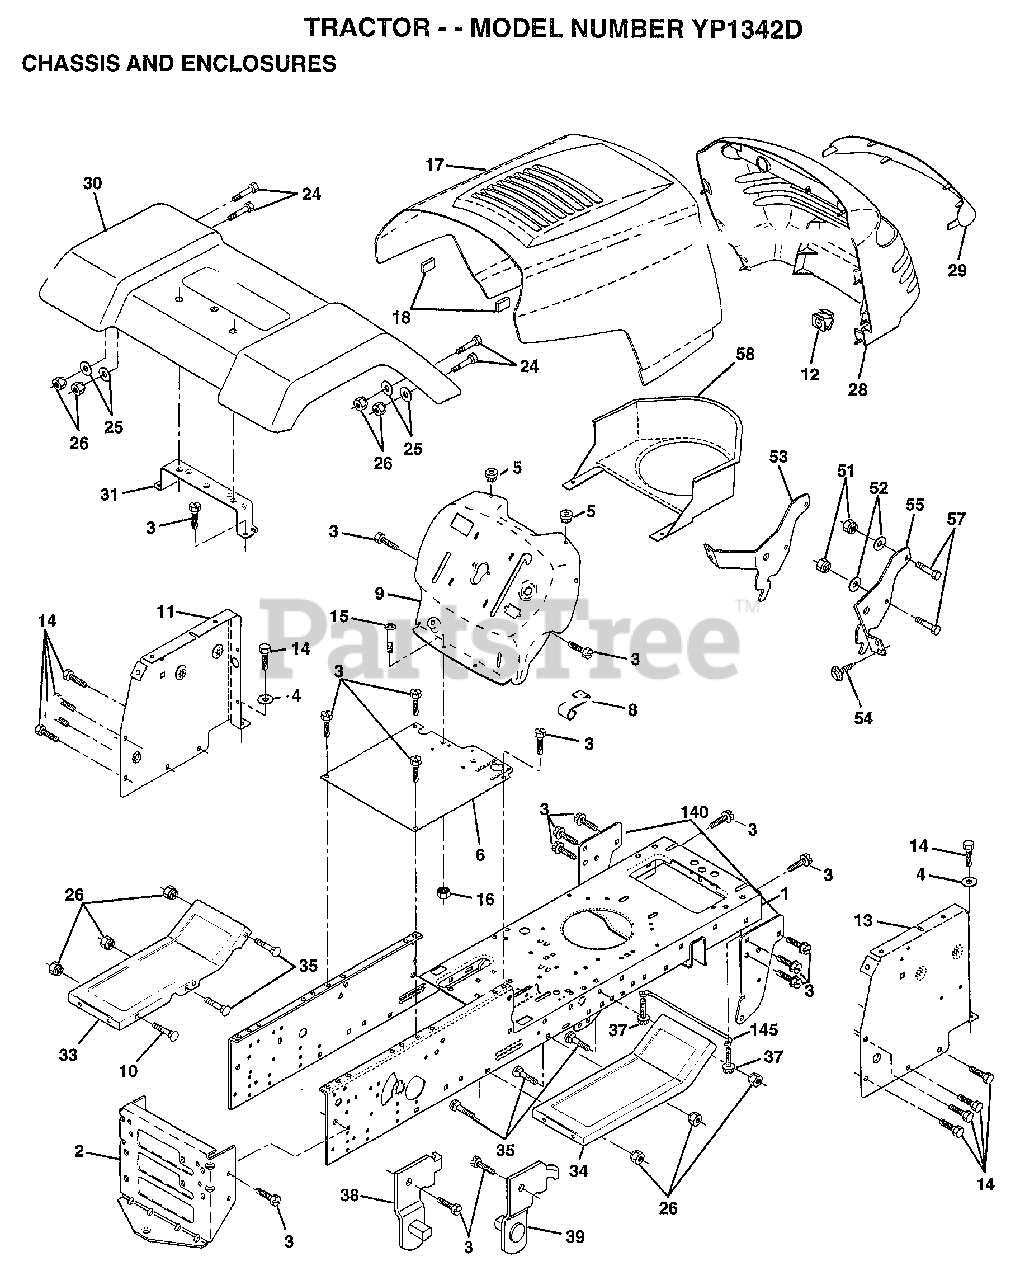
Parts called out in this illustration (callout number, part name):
3	SCREW
4	WASHER
5	BUMPER-HOOD/DASH
6	SADDLE
8	CLIP.RETAINER
9	DASH.SILKSCREEN
11	"PANEL-DASH,LH"
12	CLIP.TINNERMAN
13	"PANEL-DASH,RH"
14	SCREW LT
15	SCREW
17	"HOOD W/TRIM,MS428"
24	BOLT
25	WASHER
26	NUT
28	GRILL
29	LENS.EURO.W/DECAL
30	FENDER ASM
31	BRKT FENDER
33	FOOTREST PNT LH
34	FOOTREST.RH.LT/GT
35	BOLT
38	BRACKET ASM LH
39	BRACKET ASM RH
51	NUT
52	WASHER
53	BRACKET.GRILLE.LH
54	SCREW.HEX.WS.HD
55	BRACKET.GRILLE.RH
58	AIR DUCT
140	BRKT SUSPENSION
145	"ROD POVOT,CHASSIS"
